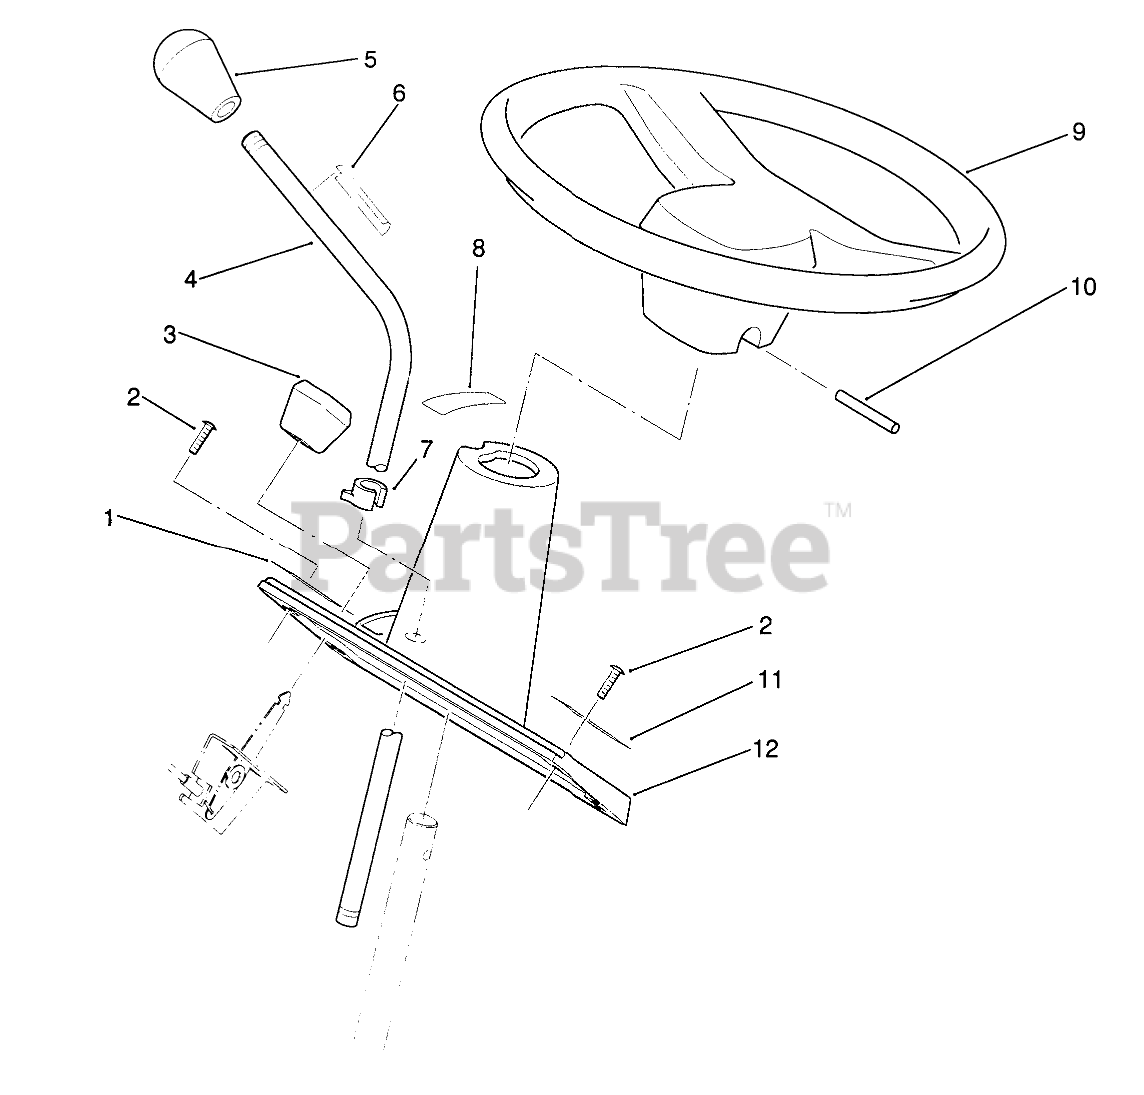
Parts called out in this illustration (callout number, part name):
1	DECAL-THROTTLE
2	SCREW
3	KNOB-THROTTLE
4	ROD-SHIFT LEVER
6	DECAL-MOTION CONTROL
7	POINTER
8	DECAL-HYDRO MOTION
9	STR'G-WHL 13" TORO
10	Pin-Roll
11	Decal-Height of Cut
12	CONSOLE
